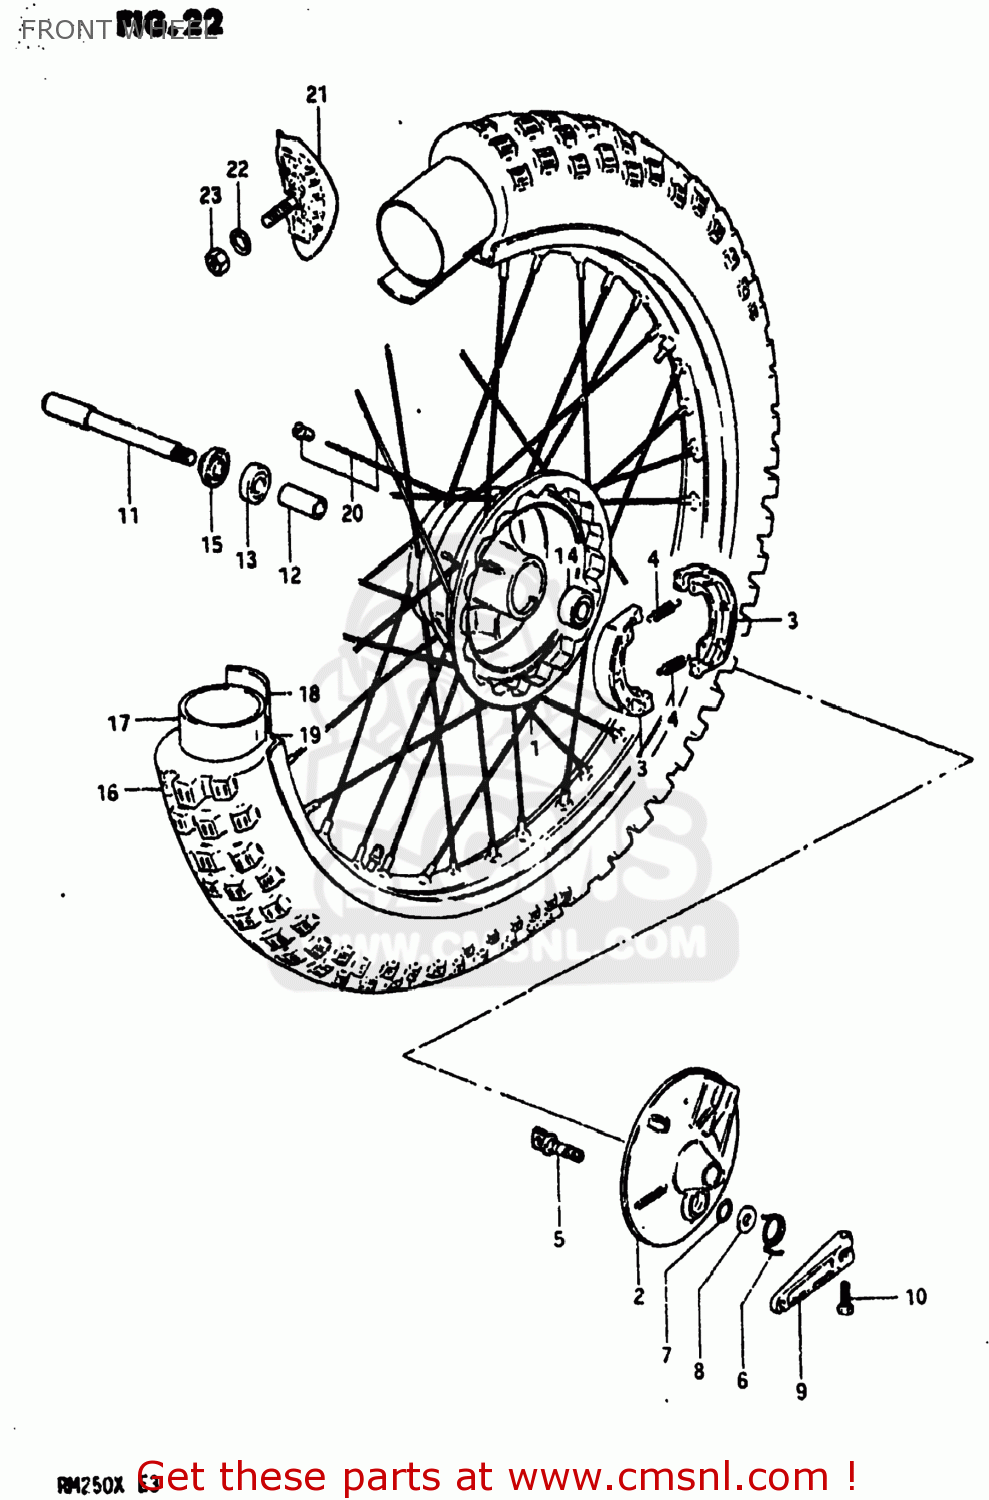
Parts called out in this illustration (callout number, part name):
1	HUB,FRONT
2	PANEL,FRONT HUB
3	SHOE,BRAKE
4	SPRING
5	CAM,FRONT BRAKE
6	SPRING
7	O RING(D:2.5,ID:11.4)
8	WASHER(12.5X20X1)
9	LEVER,FRONT BRAKE CAM
10	BOLT
11	AXLE,FRONT
12	SPACER,FRONT HUB BEARING
13	BEARING
14	BEARING
15	SPACER,FRONT AXLE,RIGHT
16	TIRE,FRONT
17	TUBE,INNER
18	PROTECTOR,WHEEL,INNER
19	RIM,FRONT WHEEL
20	SPOKE SET,FRONT
21	STOPPER,BEAD
22	WASHER
23	NUT
